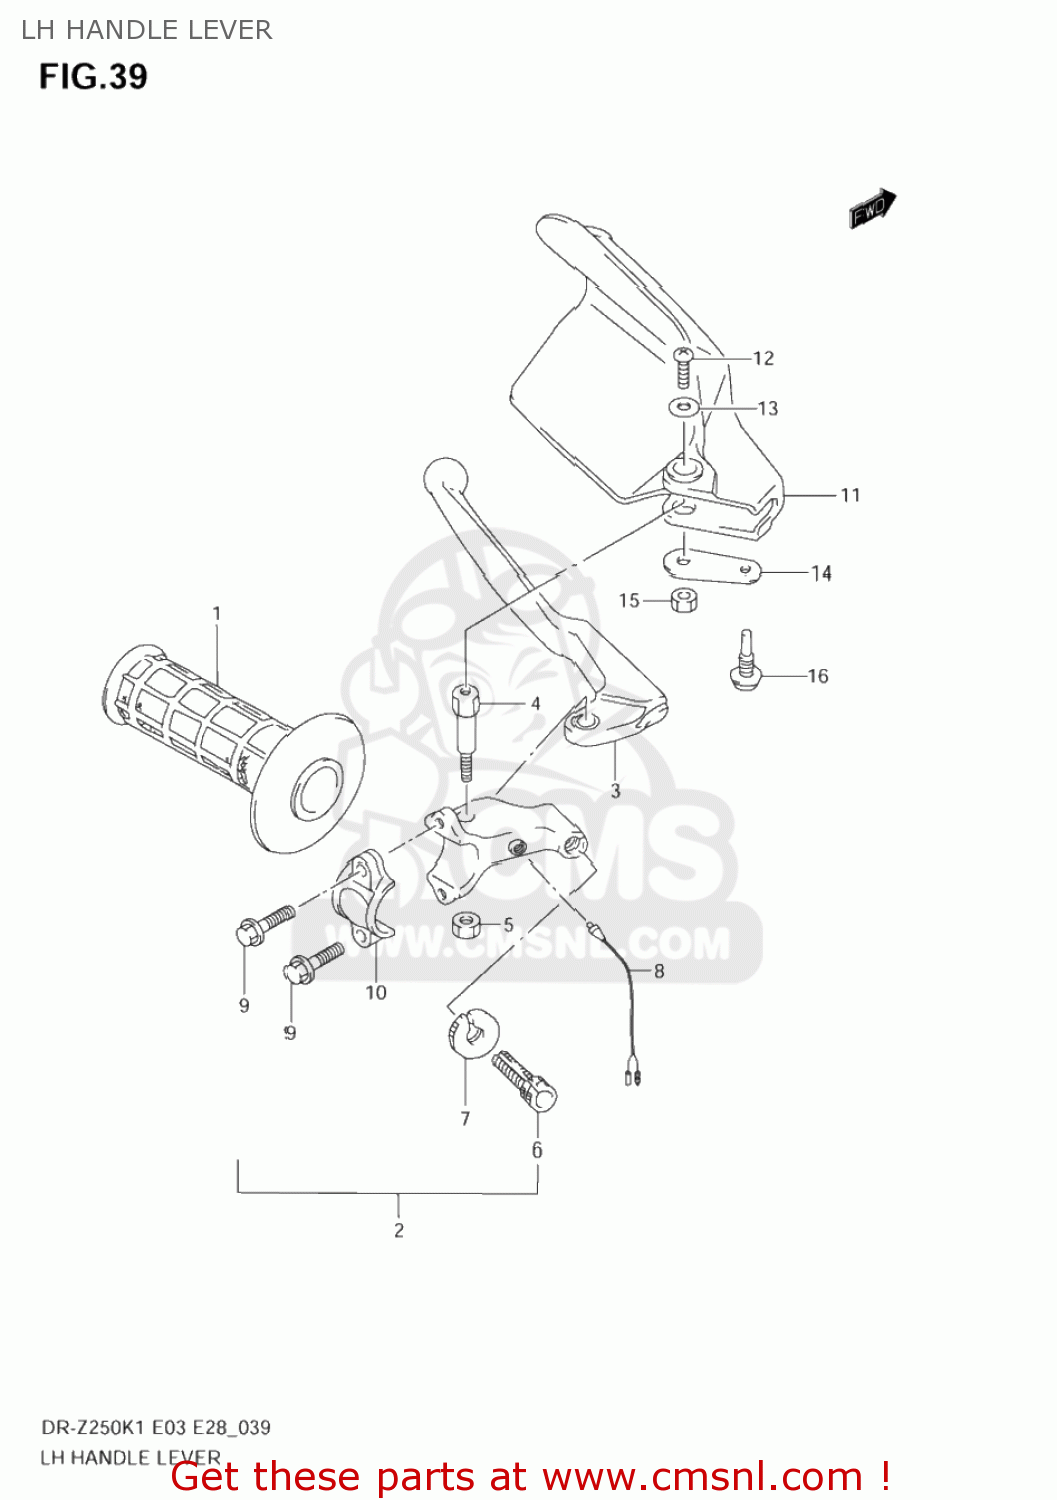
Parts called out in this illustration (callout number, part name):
1	GRIP,L
2	LEVER ASSY, CLUTCH
3	LEVER,CLUTCH
4	BOLT,LEVER PIVOT
5	NUT 6MM
6	ADJUSTER,WIRE
7	NUT,LOCK
8	SWITCH ASSEMBLY,CLUTCH
9	BOLT,BRACKET
10	BRACKET,CLUTCH LEVER HOLDER
11	COVER,KNUCKLE,L
12	SCREW
13	WASHER(5.5X16X1.2)
14	PLATE,KNUCKLE COVER,L LWR
15	NUT 6MM
16	SCREW(6X35)
